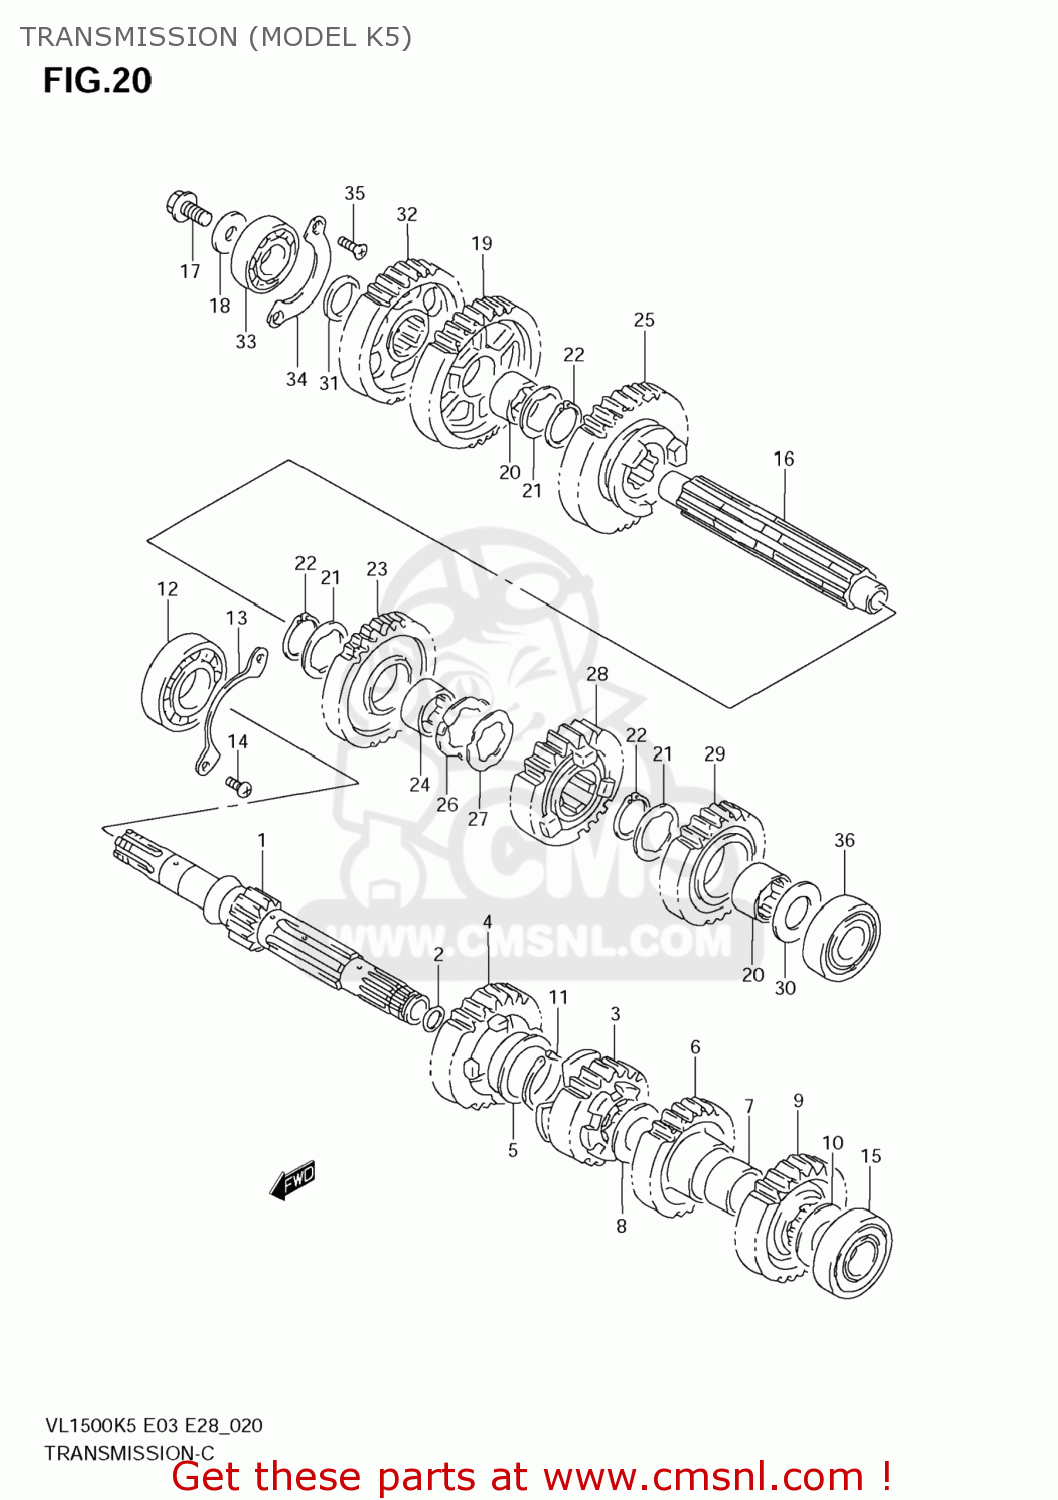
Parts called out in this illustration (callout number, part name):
1	SHAFT,COUNTER(NT:12)
2	O RING(D:1.9,ID:16.6)
3	GEAR,2ND DRIVE
4	GEAR,3RD DRIVE(NT:21)
5	BUSH(28X32X2)
6	GEAR,4TH DRIVE
7	BUSH,4TH DRIVE GEAR
8	SHIM(22X32X1)
9	GEAR,5TH DRIVE(NT:26)
10	SHIM(20X32X1)
11	CIRCLIP
12	BEARING(25X62X17)
13	RETAINER,CNTR SHAFT BEARING
14	SCREW
15	BEARING(20X52X15)
16	SHAFT,DRIVE
17	BOLT(10X24)
18	WASHER
19	GEAR,1ST DRIVEN(NT:36)
20	BUSH
21	WASHER,LOCK
22	CIRCLIP
23	GEAR,2ND DRIVEN(NT:31)
24	BUSH,3RD DRIVEN GEAR
25	GEAR,3RD DRIVEN(NT:28)
26	WASHER
27	WASHER,LOCK
28	GEAR,4TH DRIVEN(NT:25)
29	GEAR,5TH DRIVEN(NT:23)
30	WASHER
31	WASHER(22X32X3)
32	GEAR,OVER DRIVING DRIVE(NT:34)
33	BEARING(22X56X16)
34	RETAINER,CNTR SHAFT BEARING
35	SCREW(6X12)
36	BEARING(20X52X15)
